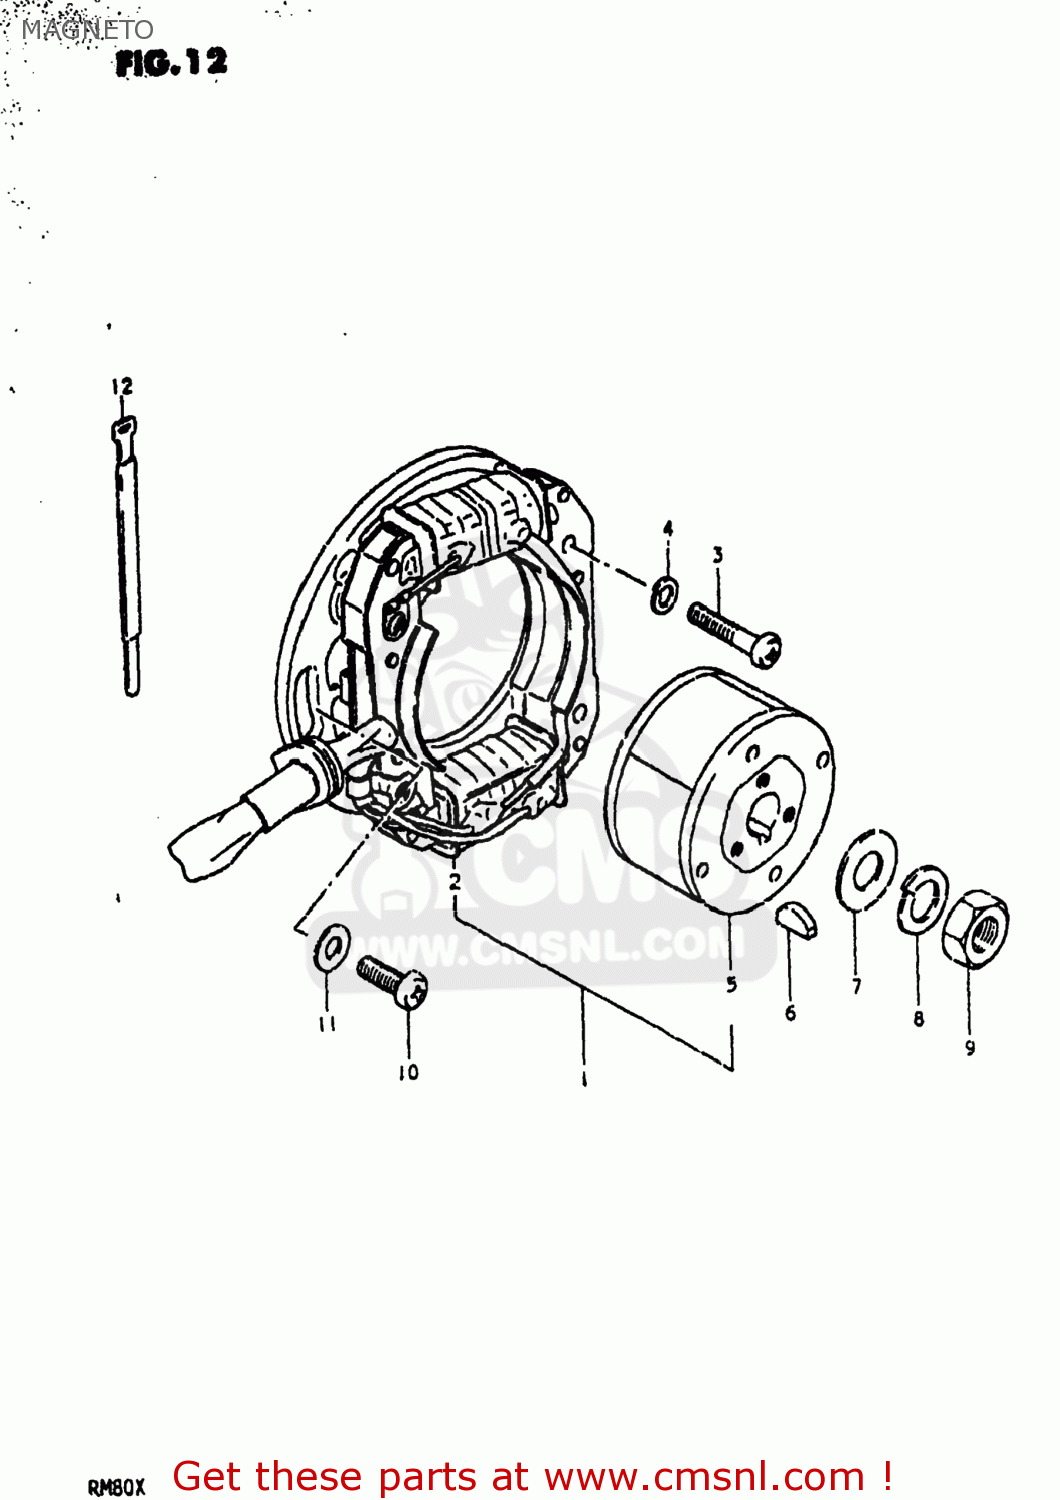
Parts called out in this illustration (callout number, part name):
1	MAGNETO ASSEMBLY
2	STATOR ASSEMBLY
3	SCREW 5X20
4	LOCK WASHER
5	ROTOR ASSEMBLY
6	KEY 4MM
7	WASHER
8	LOCK WASHER
9	NUT (10MM)
10	SCREW
11	WASHER
12	CLAMP
